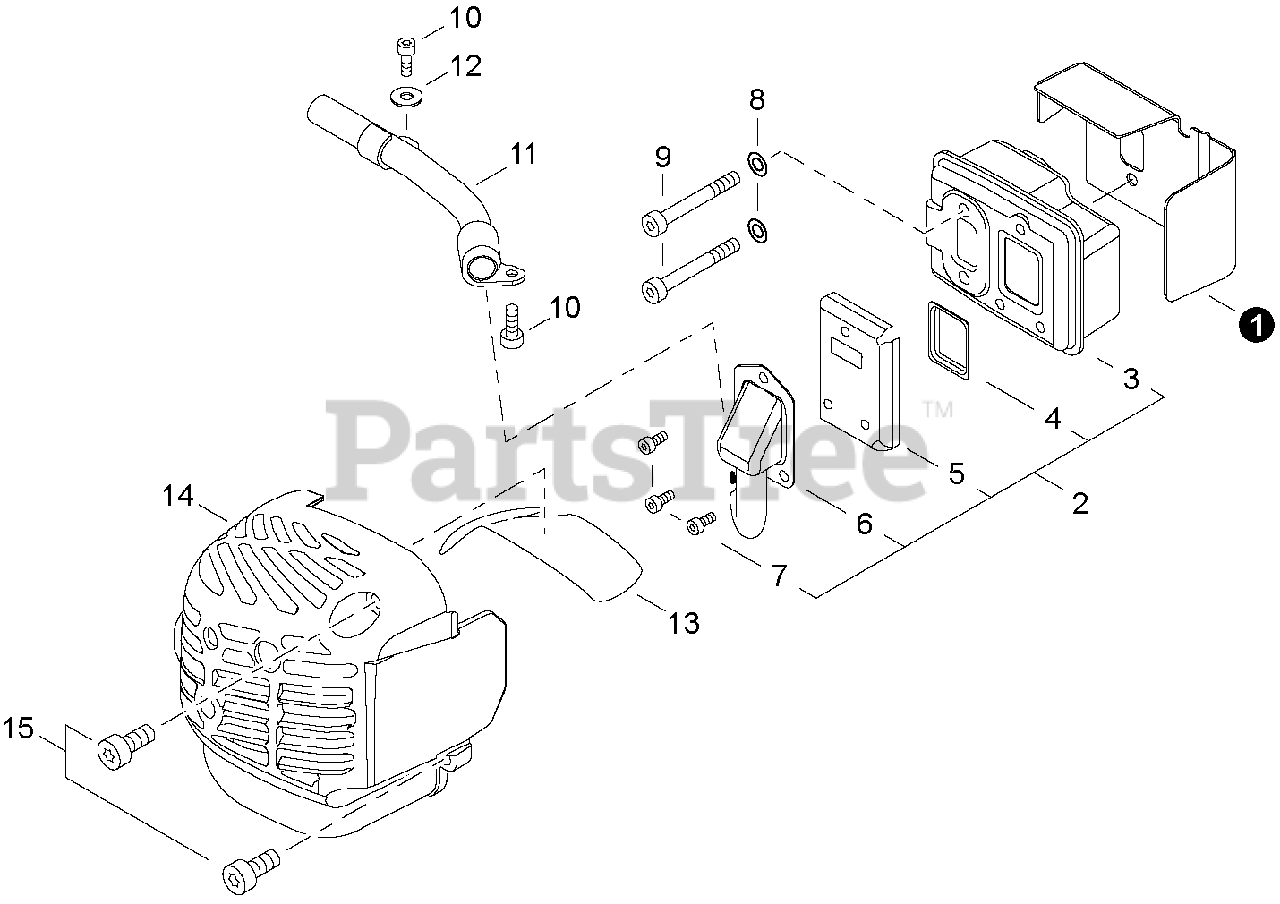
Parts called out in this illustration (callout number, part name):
1	SHIELD, EXHAUST
2	MUFFLER ASSY
3	MUFFLER
4	SCREEN, SPARK ARRESTOR
5	GASKET, EXHAUST
6	GUIDE, EXHAUST
7	SCREW - 4X8
8	WASHER - 5
9	SCREW - 5X55
10	SCREW - 5X10
11	GUIDE, EXHAUST
12	WASHER - 5
13	PLATE, INSULATOR
14	COVER, MUFFLER
15	SCREW - 5X16
